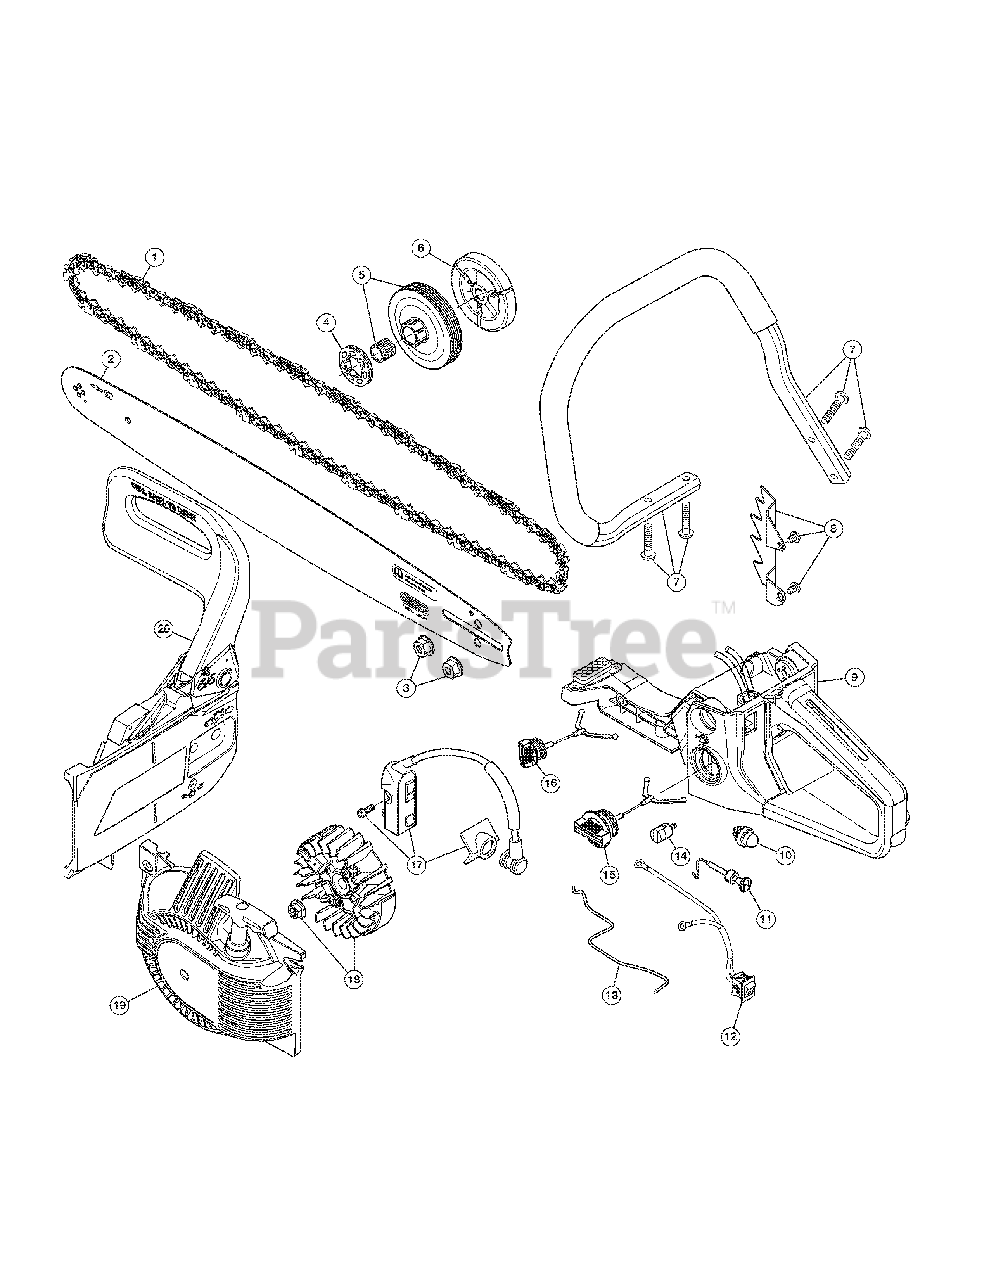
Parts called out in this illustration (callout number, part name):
1	Chain 16"
2	Chain Guide Bar
3	Guide Bar Nuts (2)
4	Sprocket
5	Clutch Drum Assembly
6	Clutch Assembly
7	Chainsaw Handle Assembly (with Screws (4))
8	Spike Plate (with Screws (2))
9	Fuel Tank Assembly
10	Primer Bulb
11	Choke Lever Assembly
12	Stop Switch Assembly
13	Throttle Rod
14	Fuel Filter
15	Fuel Cap Assembly
16	Oil Cap Assembly
17	Ignition Module Assembly (with Screws (2))
18	Flywheel Assembly
19	Starter Housing Assembly
20	Chainsaw Brake Assembly
